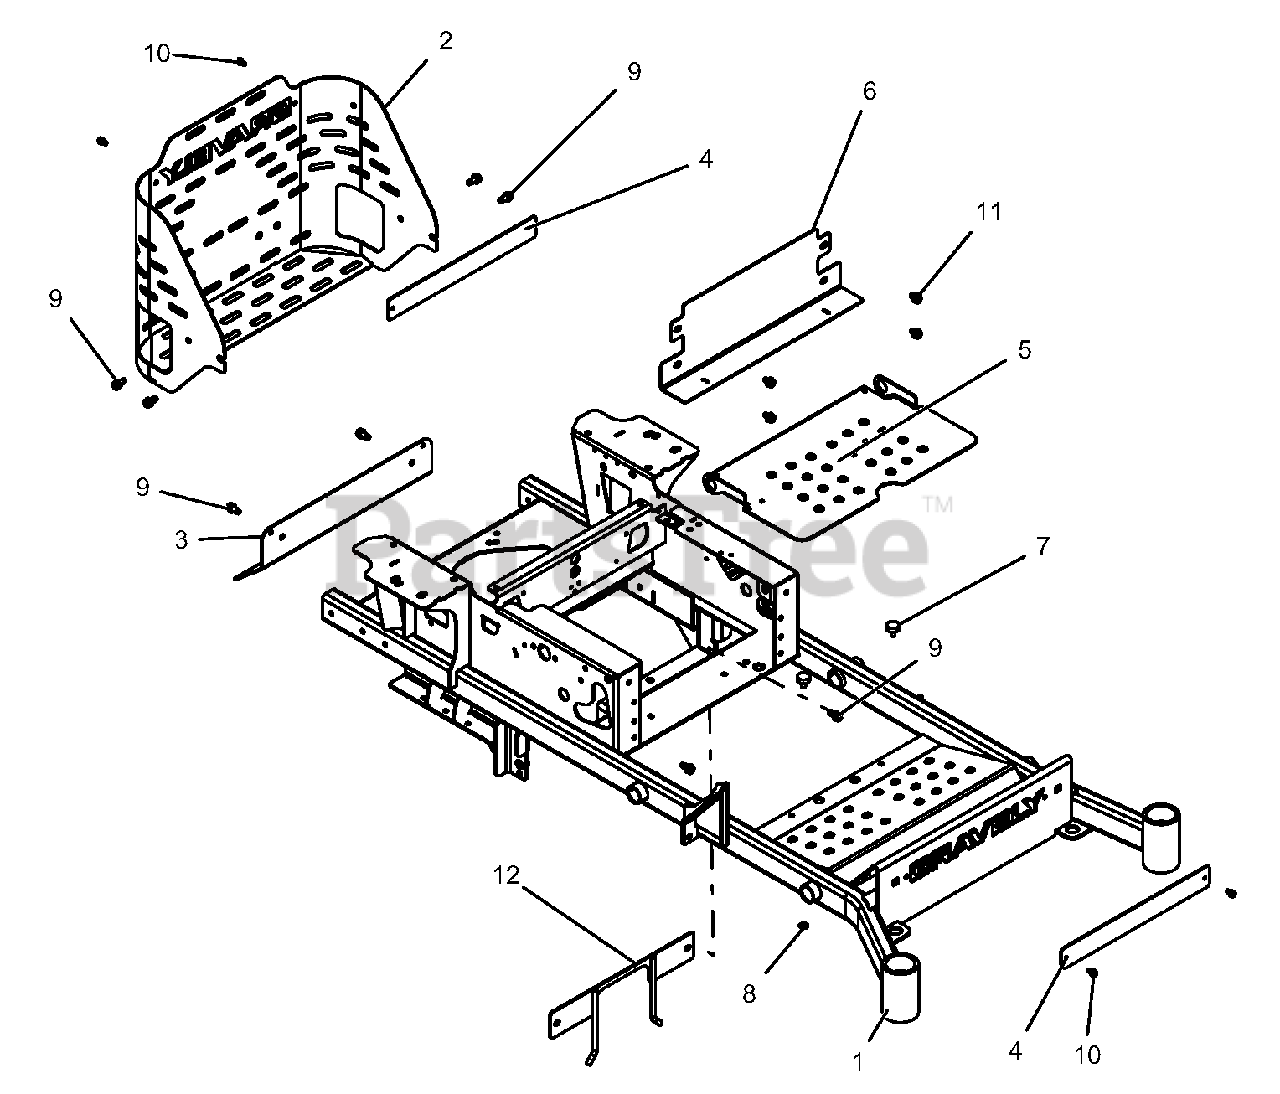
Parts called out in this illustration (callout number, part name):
1	WLDMT, PT/PT100 48-52" MAIN FRAME-RED (991200,201,204,205)
2	WLDMT, PT/PT100 60" MAIN FRAME-RED (991202,203,206)
2	WLDMT, PRO-TURN REAR BUMBER-RED
3	SHIELD, MUFFLER HEAT-BLACK
4	BUMPER, MUMPER 2.00 X 16.50 - BLK
5	FOOT PLATE
6	PLATE, PT/PT100 KICK-RED
7	BUMPER, RUBBER
8	NUT-SPNLK-FLG .312-18 YWZC
9	SCR-TAP .38-16X.75 HWH TR YWZ
10	SCR-TAP .25-20X.50 HWH TR YWZ
11	SCR-TAP .38-16X.50 HWH TR YWZ
12	WLDMT, PTO BELT FINGER-BLACK
